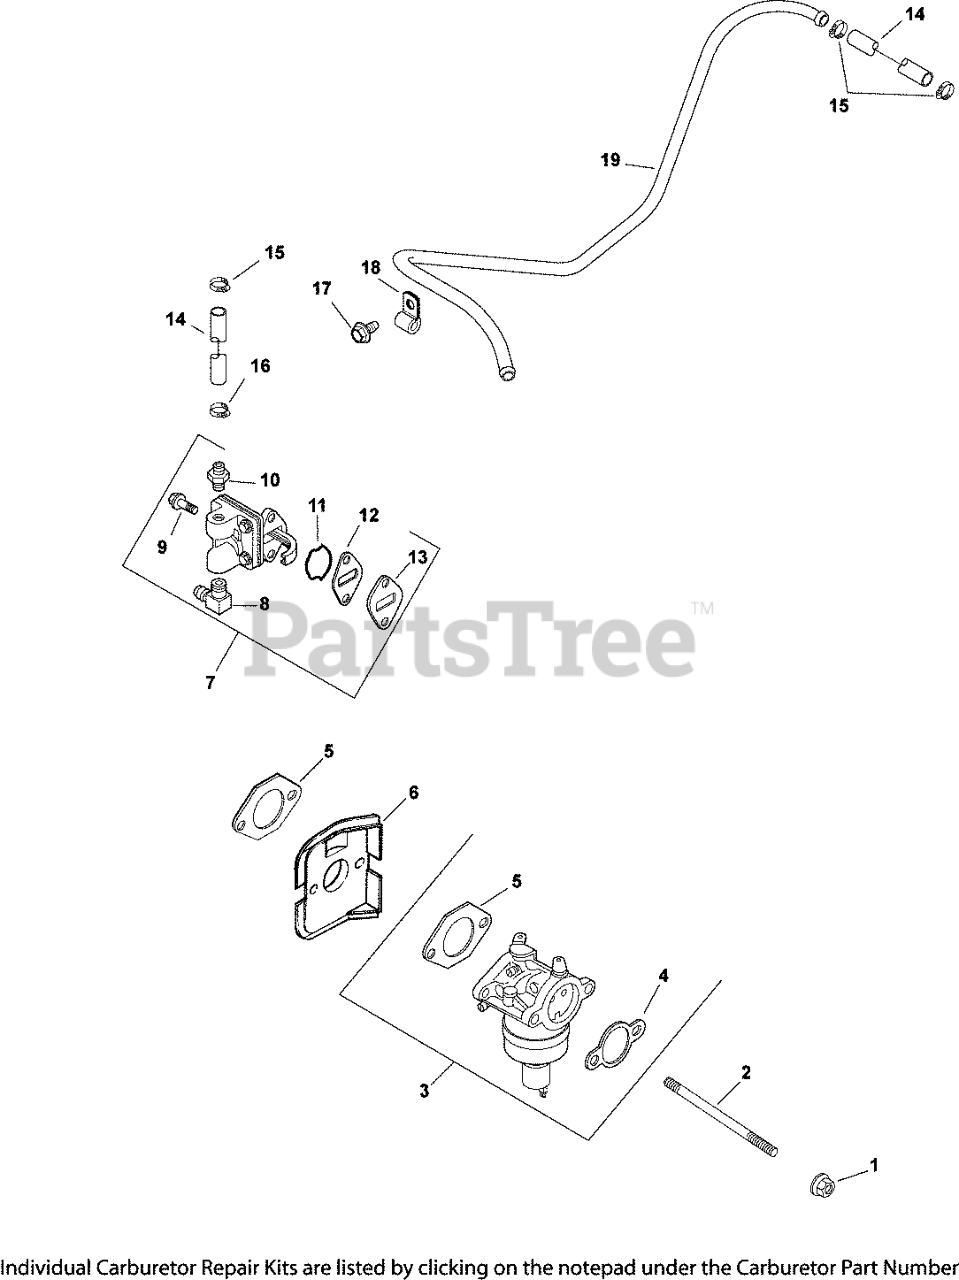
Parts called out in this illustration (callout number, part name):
1	NUT, FLG M6X1.0
2	STUD,M6X1.0X116
3	KIT, CARBURETOR w/GASKETS
4	GASKET, AIR CLEANER BASE
5	GASKET, CARBURETOR
6	DEFLECTOR, HEAT
7	KIT, FUEL PUMP
8	CONNECTOR, 90 DEG. HOSE
9	SCREW, LBD SKT M6x1.0x20-(#25086403S)
10	KIT, STRAIGHT FITTING
11	O-RING, FUEL PUMP
12	GASKET, FUEL PUMP
13	SPACER, FUEL PUMP
14	HOSE,LW PERM.FUEL 24.00"-USE 25 111 81-S
15	CLAMP, HOSE (KM)-USE 25 237 31-S
16	CLAMP, BAND SPRING HOSE-(#2523737S)
17	SCREW, FLG THD FRM M5X.8X10
18	CLIP, TUBE & WIRING (KM)
19	LINE, FUEL
